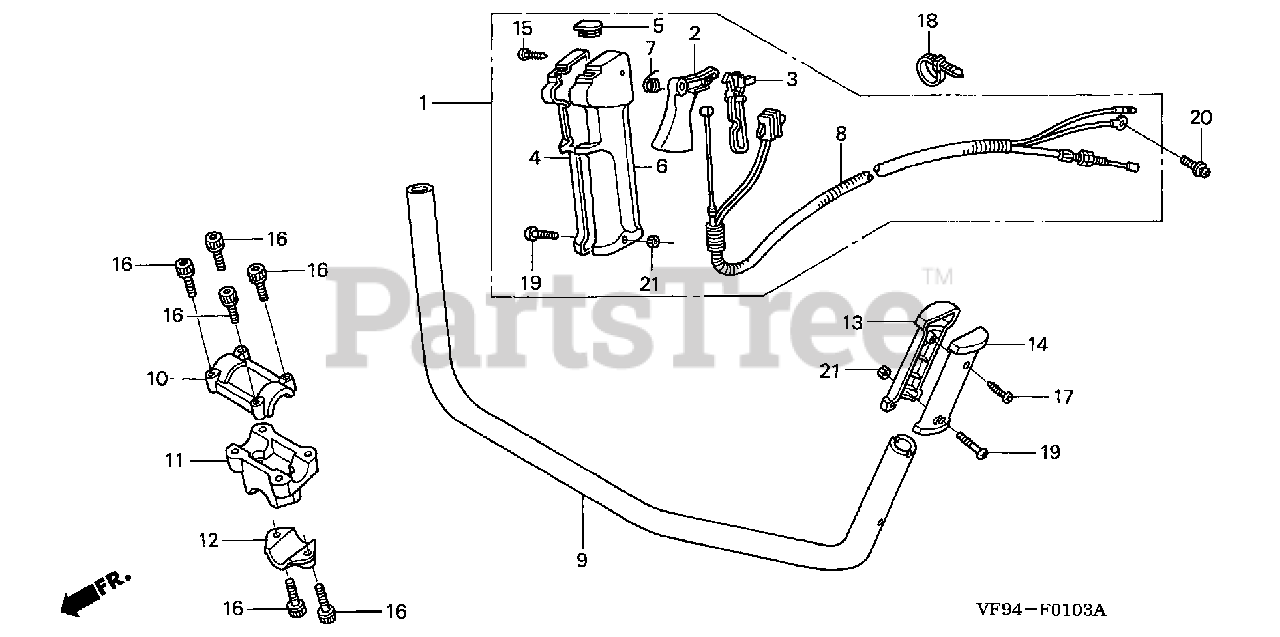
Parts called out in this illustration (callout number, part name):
1	LEVER ASSY., THROTTLE (U)
2	LEVER, THROTTLE
3	LEVER, THROTTLE LOCK
4	GRIP, R. THROTTLE LEVER
5	CAP, THROTTLE LEVER
6	GRIP, L. THROTTLE LEVER
7	SPRING, THROTTLE LEVER
8	WIRE HARNESS ASSY.
9	PIPE, HANDLE
10	HOLDER A, HANDLE
11	HOLDER B, HANDLE
12	HOLDER C, HANDLE
13	GRIP A, HANDLE
14	GRIP B, HANDLE
15	SCREW, TAPPING (4X20)
16	BOLT, SOCKET (6X30)
17	SCREW, TAPPING (5X16) (PO)
18	BAND, WIRE HARNESS
19	SCREW, PAN (5X30)
20	SCREW-WASHER (5X12)
21	NUT, HEX. (5MM)
